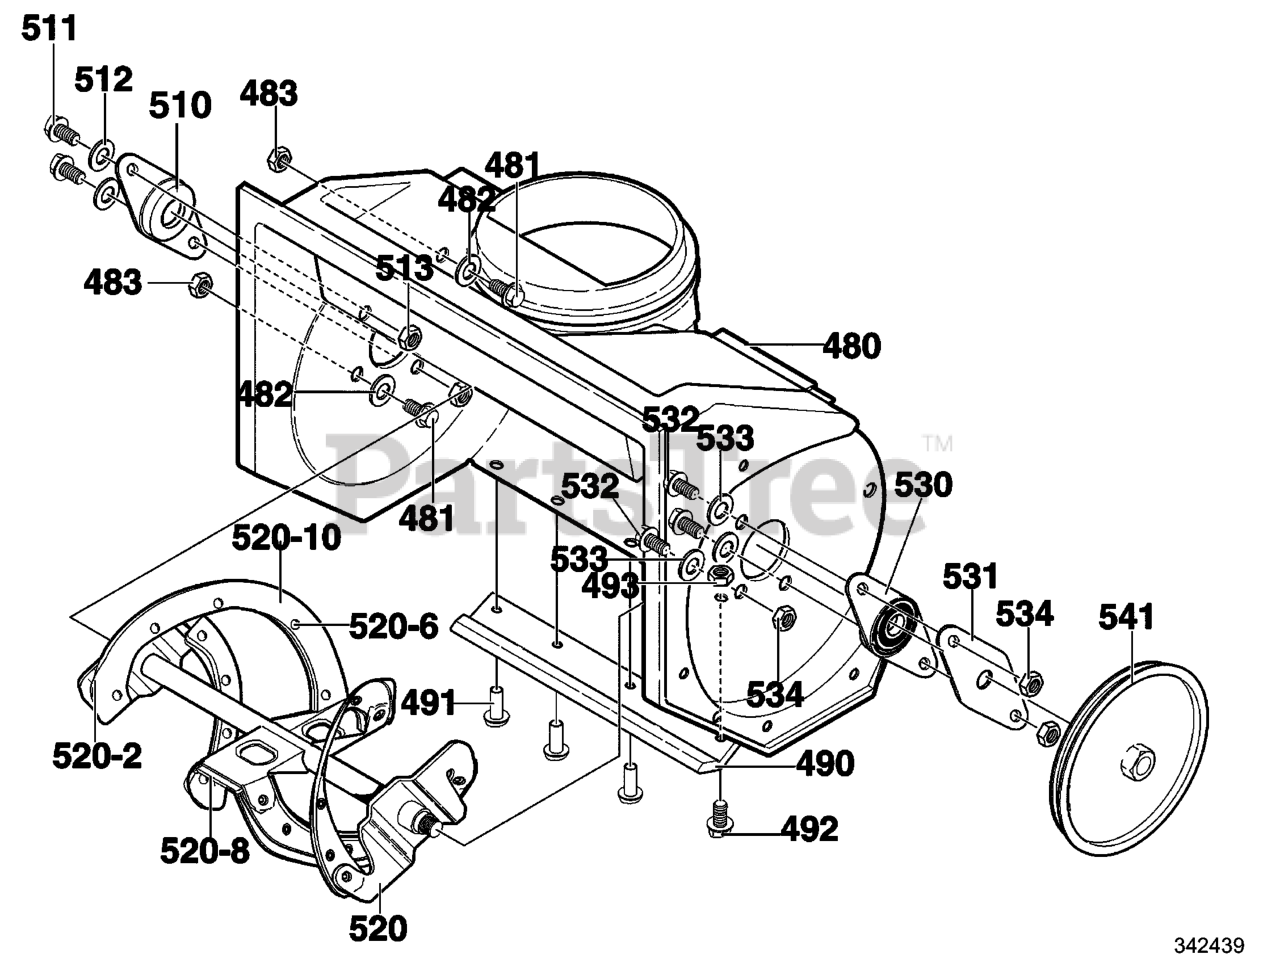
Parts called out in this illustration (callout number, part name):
480	HOUSING, ASSY
481	SCREW, 1/4-20X.75
482	WASHER, FLAT .281X.63X.065
483	NUT, 1/4-20 REGHEXCTRLK
490	BLADE, SCRAPER
491	RIVET, OVSET
492	SCREW, 1/4-20X.75
493	NUT, CNTRLK 1/4-20
510	BEARING, FLANGE
511	SCREW, 1/4-20X1.00
512	WASHER, FLAT .281X.63X.065
513	NUT, CNTRLK 1/4-20
520	AUGER, ASSY
520-2	BLADE, AUGER
520-6	RIVET
520-8	BLADE, CENTER
520-10	AUGER & BLADE SUPPORT
530	BEARING & PLATE ASSY.
531	PLATE, RETAINER
532	SCREW, 1/4-20X.63
533	WASHER, FLAT .281X.63X.065
534	NUT, 1/4-20 REGHEXCTRLK
541	PULLEY, V3L 6.00
